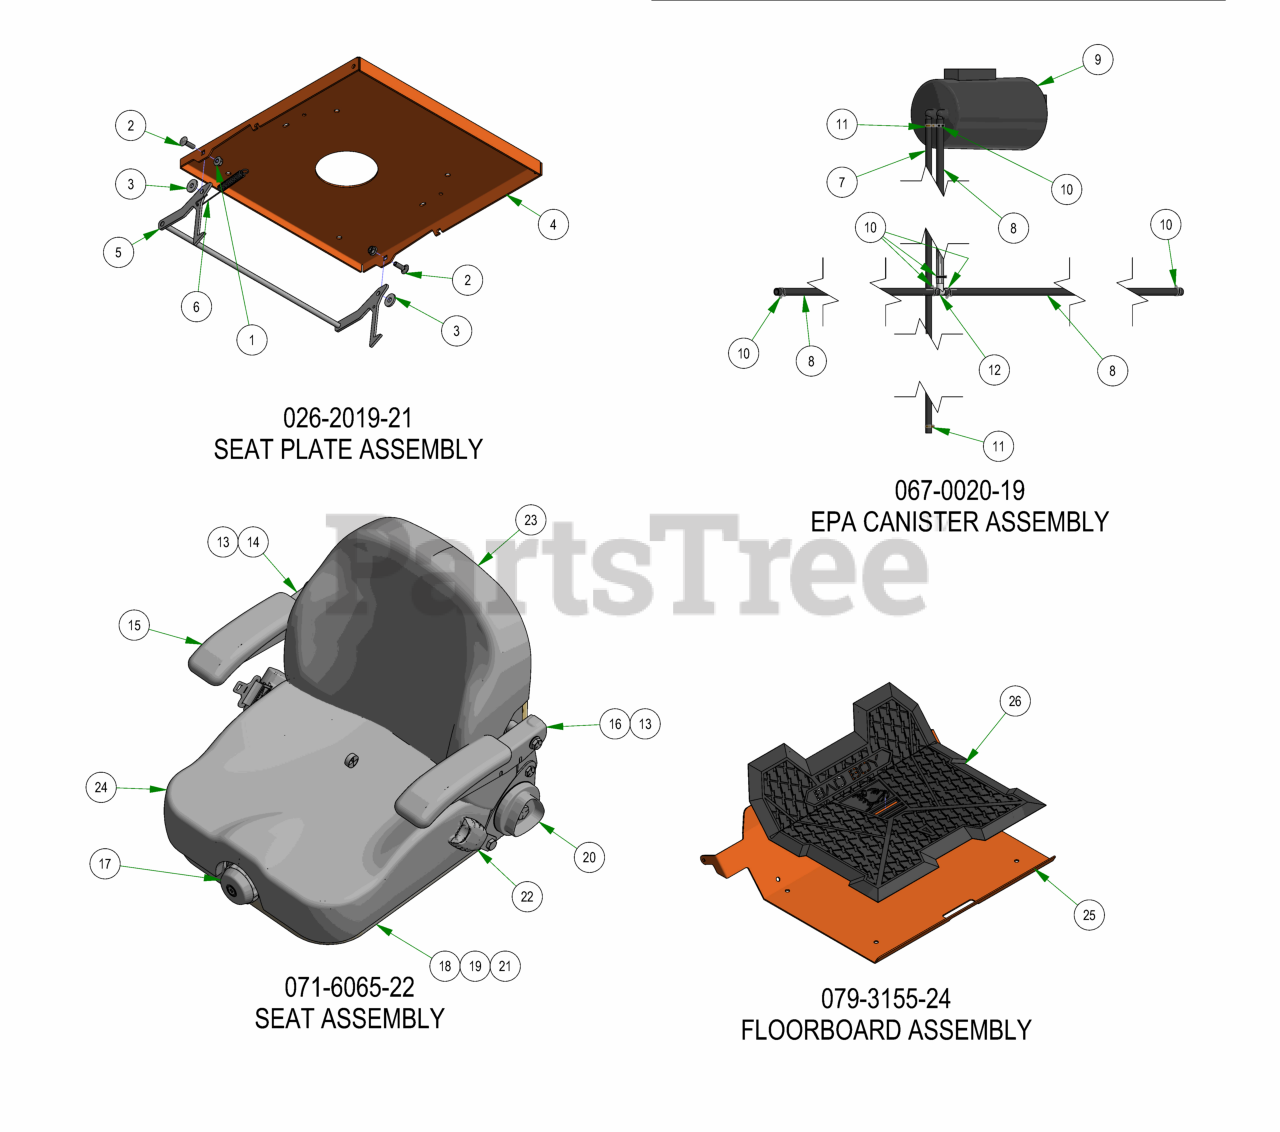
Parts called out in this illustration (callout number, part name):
1	5/16-18 NYLON INSERT FLANGE LOCKNUT ZINC
2	5/16-18 X 1 CARRIAGE BOLT (GR.8) ZINC
3	.360 ID X .983 OD X .120 THICK FLAT WASHER NYLON
4	R-SERIES SEAT PLATE
5	Seat Latch Rod Assembly
6	Brake Spring
7	3/16" Vinyl Tubing, 66" Long
8	1/4" Vinyl Tubing 38" Long
9	Carbon Canister
10	3/16 Vinyl Clamp
11	3/16" Vinyl Hose Clamp
12	fuel line T
13	Set of Armrests-SS Front Adj
14	RH Armrest-Selfskin Front Adj
15	Black Selfskin-Arm Pad Only
16	LH Armrest-Selfskin Front Adj
17	Weight Adjust Indicator Knob Assy
18	4" Single Locking Track Kit
19	Delta Plunger Switch - N.O.
20	Recliner Adjustment Knob-New
21	Bellows w/Hardware
22	2" Retractable Belt Kit w/Spacers
23	Back Cover for I3M - Recl - Logos
24	Cushion Cover Kit for I3M-Logo
25	2024 R-Series Floorboard
26	2024 R-Series Floor Mat
